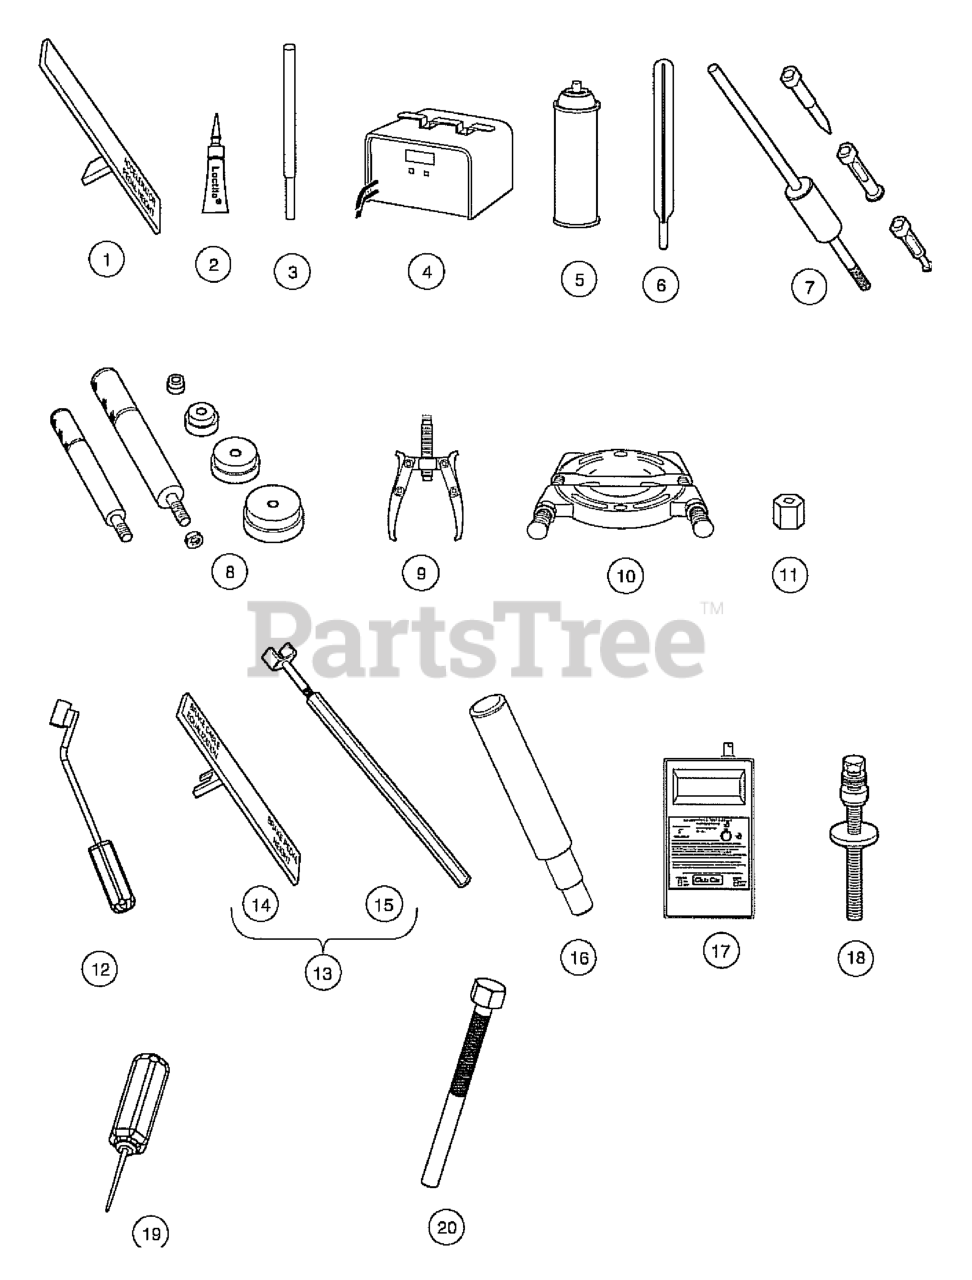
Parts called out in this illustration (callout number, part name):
1	TOOL, ACCEL. PEDAL ADJUSTMENT
2	Adhesive, Guide Ring, 3-Gram Tube
4	Battery Discharge Machine, 36/48 Volt
5	BATTERY TERMINAL PROTECT SPRAY
6	BATTERY THERMOMETER
7	BEAR & OIL SEAL REMOVER ASM
8	BEARING DRIVER SET
9	BEARING PULLER
10	BEARING PULLER WEDGE ATTACH.
11	BRAKE ADJUSMENT SOCKET TOOL
12	BRAKE CABLE RELEASE TOOL
13	Brake Pedal Adjustment Tool Kit
14	Brake Pedal Adjustment Tool
15	Brake Pedal Tension Tool
16	Connecting Rod Small End Bushing Tool
17	Calibration Test Module
18	CAM INSTALLATION TOOL
19	Charger Bezel Tool
20	TOOL, REMOVAL, CLUTCH, GAS/DSL
